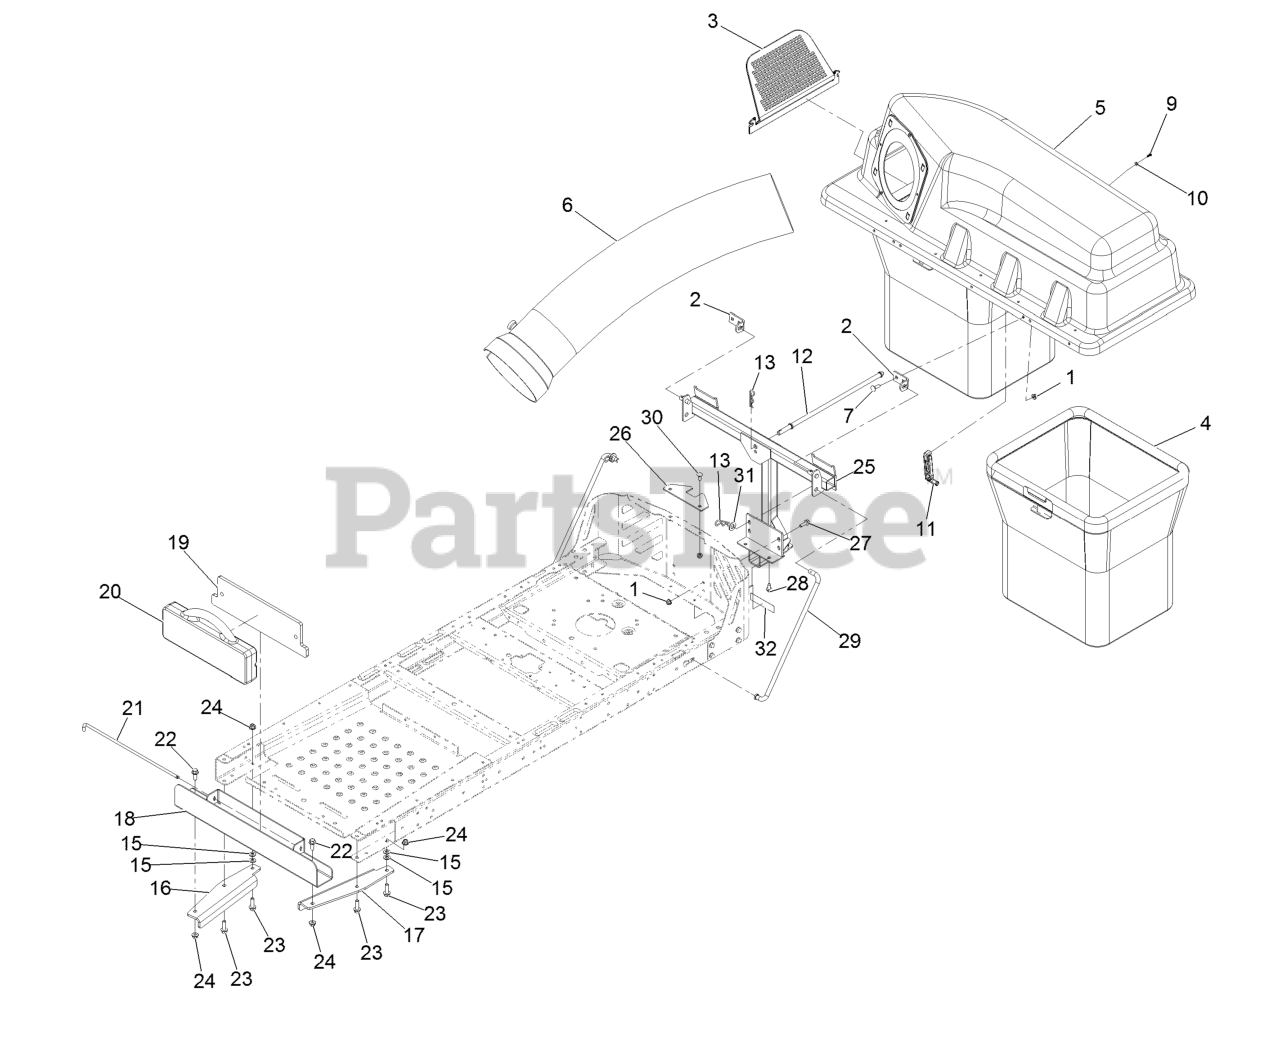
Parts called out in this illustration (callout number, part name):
1	NUT-HF, NI
2	BRACKET-PIVOT, HOPPER
3	SCREEN-BAGGER
4	BAG ASM
5	BAGGER TOP ASM
6	TUBE-BAGGER
7	BOLT-CARR
9	SCREW-PLASTIC, PTH
10	WASHER-FLAT
11	LATCH-RUBBER
12	ROD-HOOD, DOWN (HOLD)
13	PIN-HAIR
15	WASHER-FLAT
17	BRACKET-BAGGER WEIGHT, LH
18	CHANNEL-WEIGHT, BAGGER
20	WEIGHT-35 POUND
21	PIN-WEIGHT
22	SCREW-HHF 3/8-16 X 1
23	SCREW-HHF
24	NUT-HF, NI
25	PIVOT FRAME ASM
26	BRACKET-STABILIZER
27	SCREW-HHF
28	Screw-HWH 5/16-18 X 3/4 Tf
29	ROD-SUPPORT
30	BOLT-CARR
31	WASHER-FLAT
